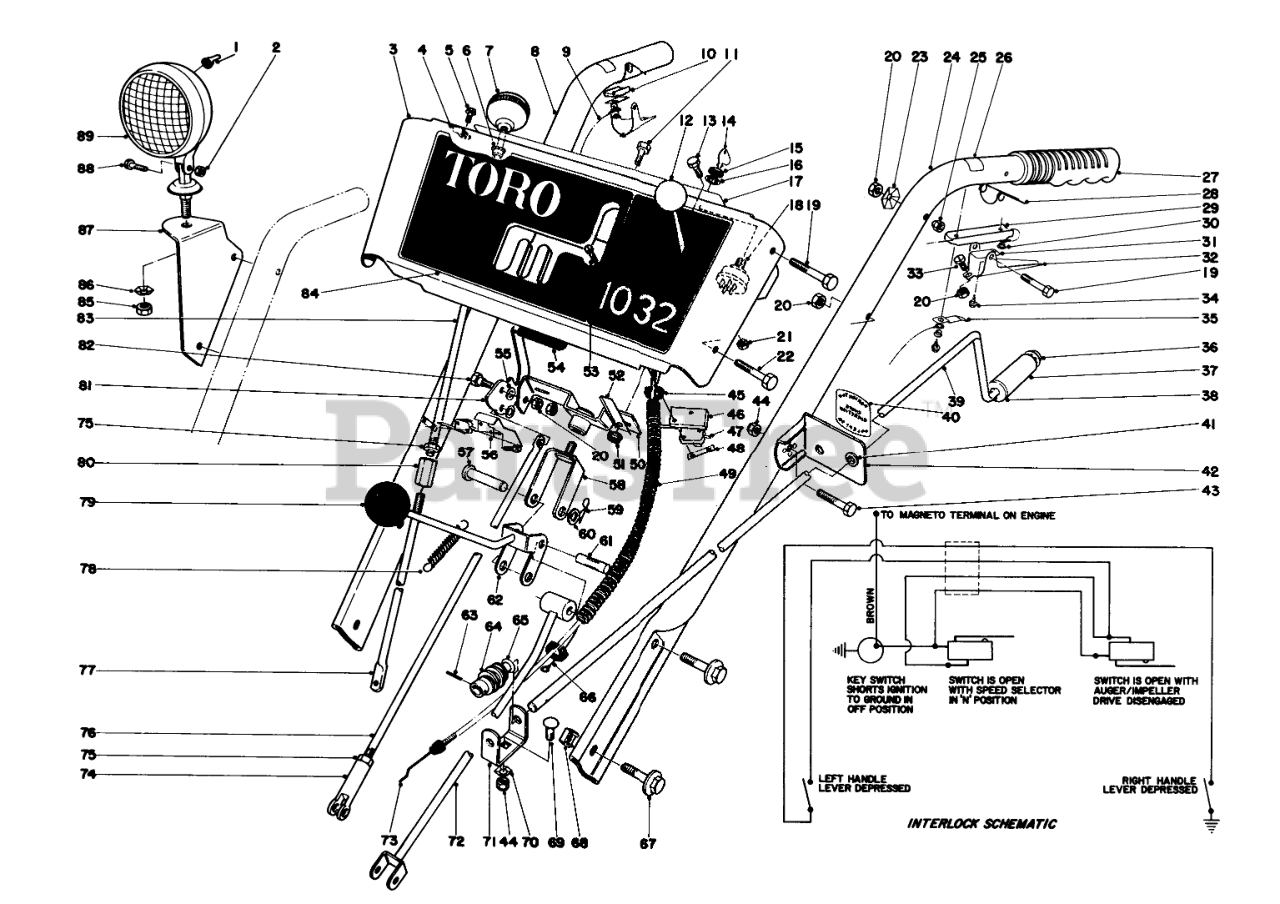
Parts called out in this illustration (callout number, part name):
1	BOOT-SWITCH
2	NUT-HEX, SIDE DEFORM
3	Escutcheon Plate (Incl. Ref. #17 & 84)
4	PLASTIC CLIP
5	SCREW-HWHTF
6	Bushing
7	KNOB-LEVER
8	Handle Right
9	Wire Harness Interlock
10	Insulator
11	SCREW-HH
12	KNOB-CONTROL
13	HEX HEAD SEMS 10-24X1/2
14	Key
15	NUT-HH
16	Lockwasher
17	Decal-Escutcheon Back
18	SWITCH-STARTER
19	SCREW-HH
20	NUT-LOCK, CONE
21	Nut
22	SCREW-HH
23	Washer
24	Handle Left
25	NUT-CAP
26	Decal Safety Interlock
27	Grip Handle
28	INTERLOCK SPRING
29	DUAL BRKT INSULATOR
30	WASHER INSULATOR
31	INTERLOCK CONTACT
32	SAFETY INTRLOCK LEVER
33	Nylon Pan Hd. Screw
34	Screw
35	CONTACT BRACKET
36	RETAINER-PUSH ON
37	CHUTE CONTROL GRIP
38	WASHER-FLAT
39	ROD CHUTE CONTROL
40	Decal Chute Direction
41	Bushing
42	Bracket Chute Control Mounting (Incl. Ref. #40 & 41)
43	SCREW-HH
44	NUT-LOCK, CONE
46	SWITCH MTG PAD
47	MICRO SWITCH
48	NUT-SPEED
49	Cover Harness
50	SWIVEL BLOCK WA
51	NUT-LOCK, HHF
52	Retainer Wire
53	SCREW-SPH
54	AUGER CLUTCH HND GRIP
55	WASHER-PLAIN
56	SWITCH BRKT
57	PIN-CLEVIS
58	Pivot Bracket
59	PIN-HAIR
60	WASHER-FLAT
61	3/8 X 1-1/4 ROL
62	SHIFT ROD WA
63	PIN-SPRING
64	GEAR-WORM, CHUTE
65	WASHER-SPRING
66	Ignition Wire Harness
67	SCREW-HHF
68	Retained Nut
69	SCREW-CARR
70	WASHER-LOCK
71	WORM BRACKET
72	Trunnion
73	Throttle Contrl
74	Clevis
75	NUT-HJ
76	DRAG LINK
77	LOWER WHL CLUTCH ROD
78	CONT ROD SPRING 0
80	WHL ROD COUPLING
81	Auger Clutch Handle
82	SCREW-SHOULDER
83	Rod Wheel Clutch
84	Decal-Escutcheon
85	NUT-HEX
86	LOCKWASHER-PYRAMID
87	Lamp Mount
88	SCREW-HH
89	HEADLAMP ASM
